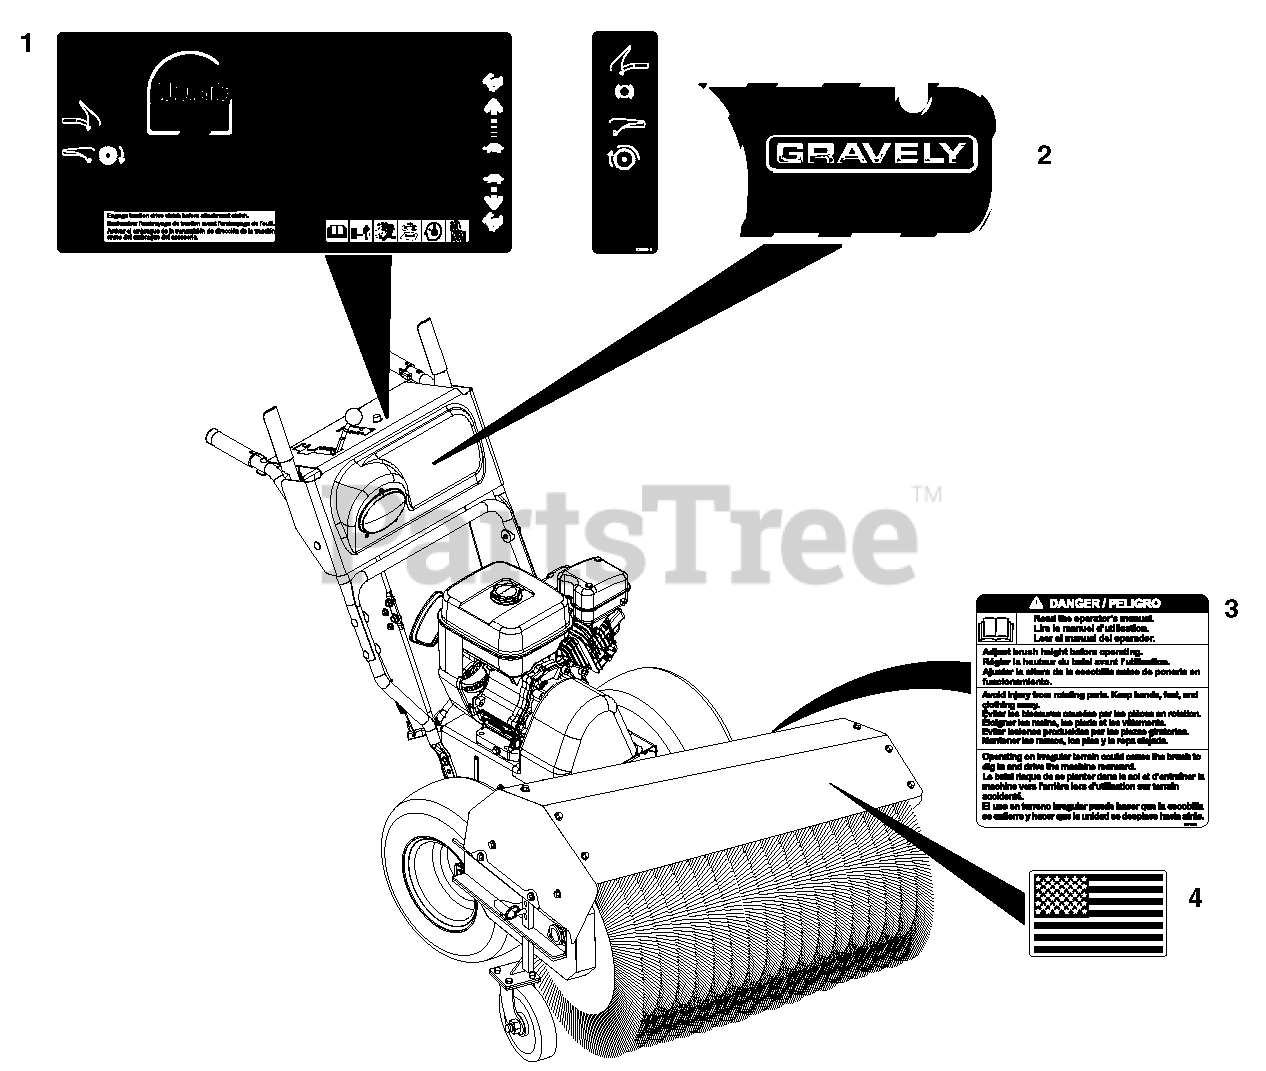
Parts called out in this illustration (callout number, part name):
1	Decal, Control PB
2	Decal, Front Dash Brush
3	Decal, Caution
4	Decal, American Flag
